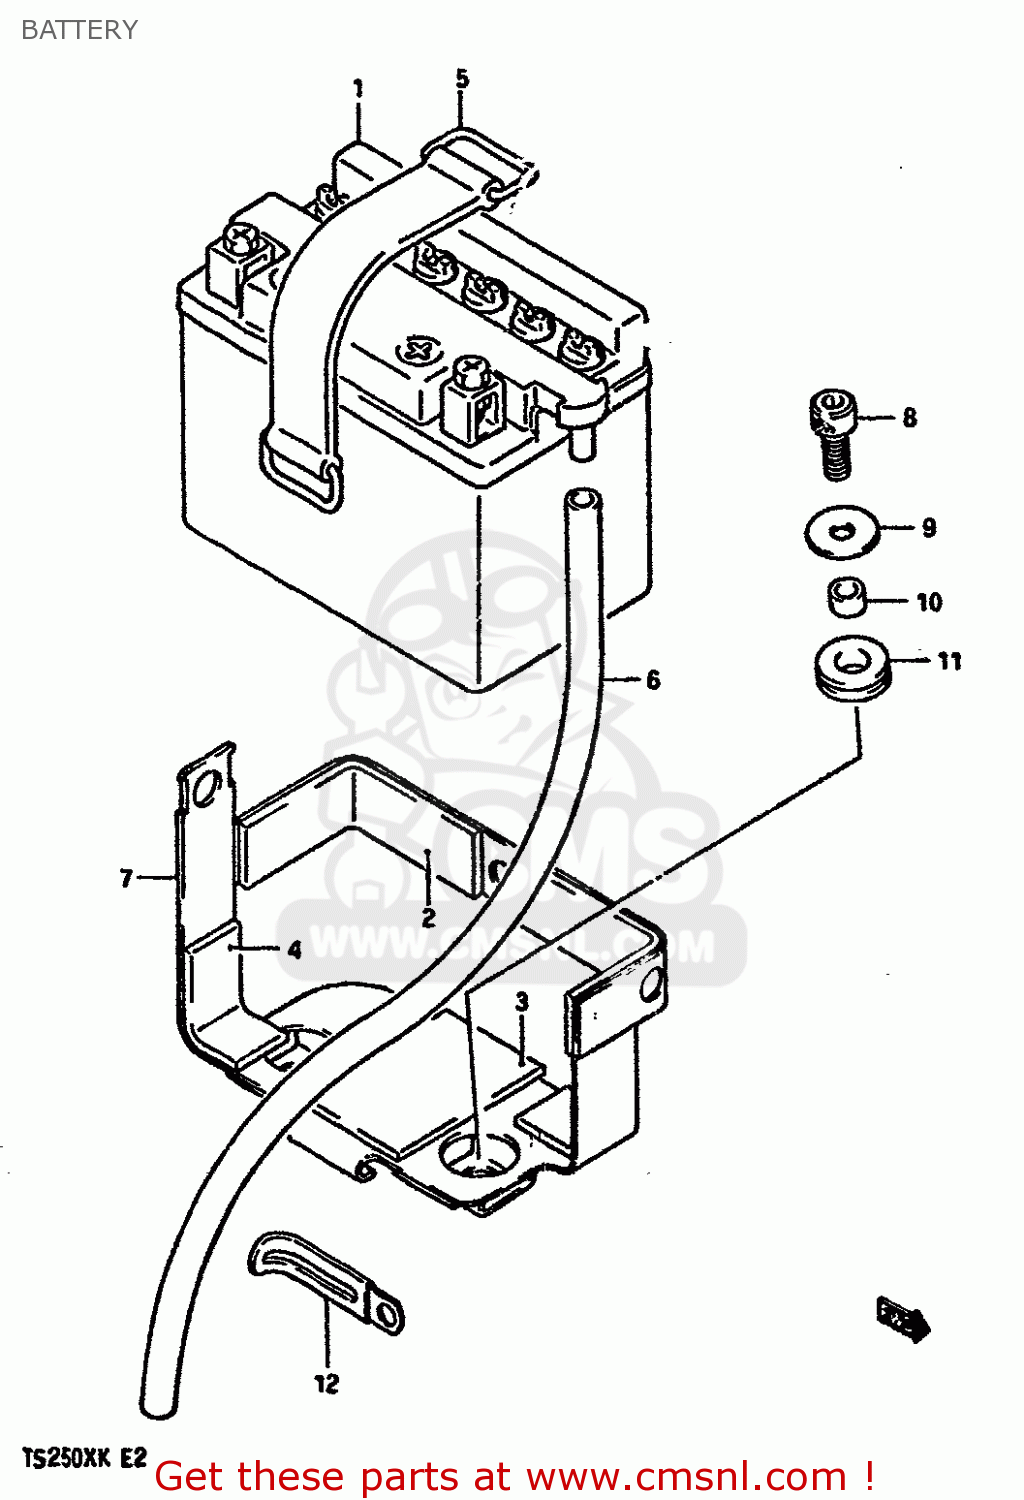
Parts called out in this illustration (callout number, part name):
1	BATTERY ASSY(YB4L-B,12V4.2AH)
2	PROTECTOR,BATTERY
3	PROTECTOR,BATTERY
4	PROTECTOR,20X9
5	BAND
6	HOSE,BATTERY EXHAUST
7	HOLDER,BATTERY
8	BOLT
9	WASHER (6.5X20X1.2)
10	SPACER
11	CUSHION
12	CLAMP
